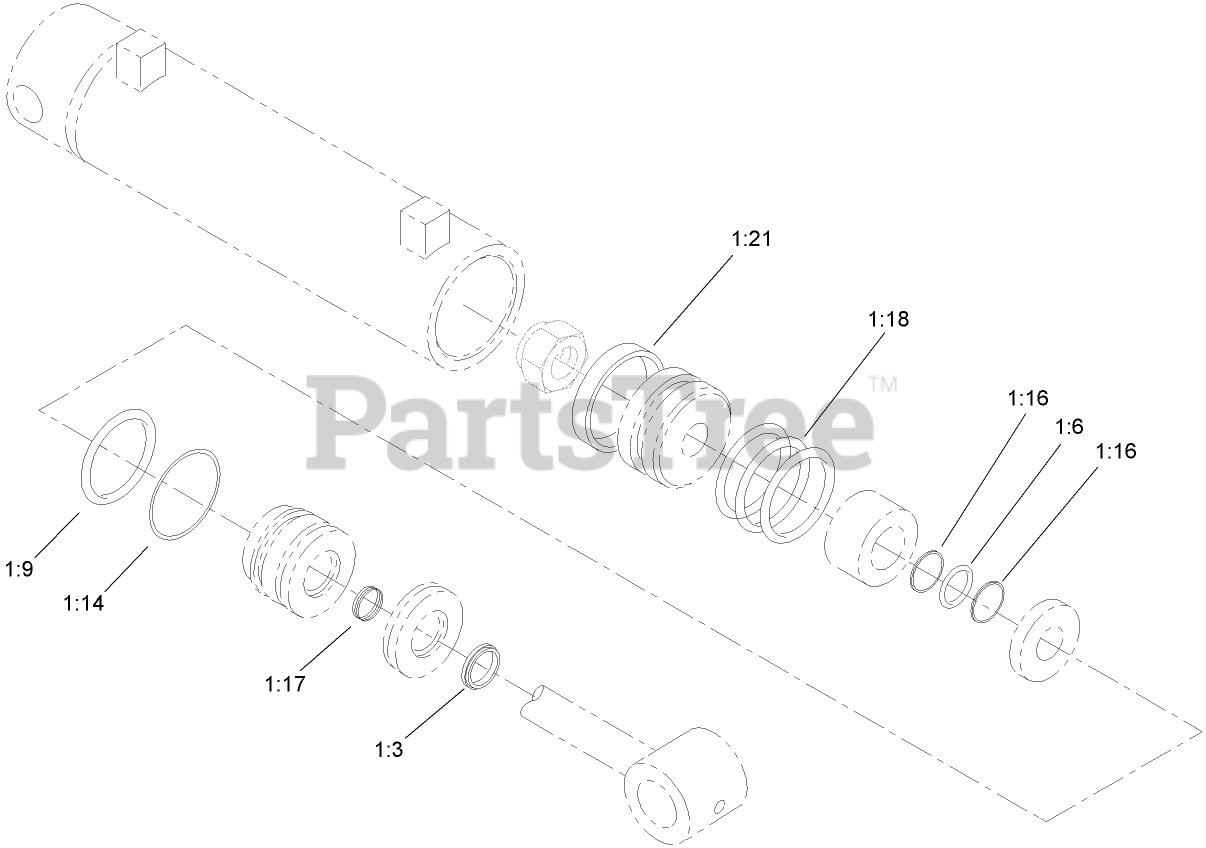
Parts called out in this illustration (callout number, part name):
1	CYLINDER SEAL KIT
1:3	Seal-Wiper
1:6	O-Ring
1:9	O-Ring
1:14	Ring-Backup
1:16	Ring-Backup
1:17	PACKING ASSEMBLY
1:18	PACKING ASSEMBLY
1:21	Ring-Wear
